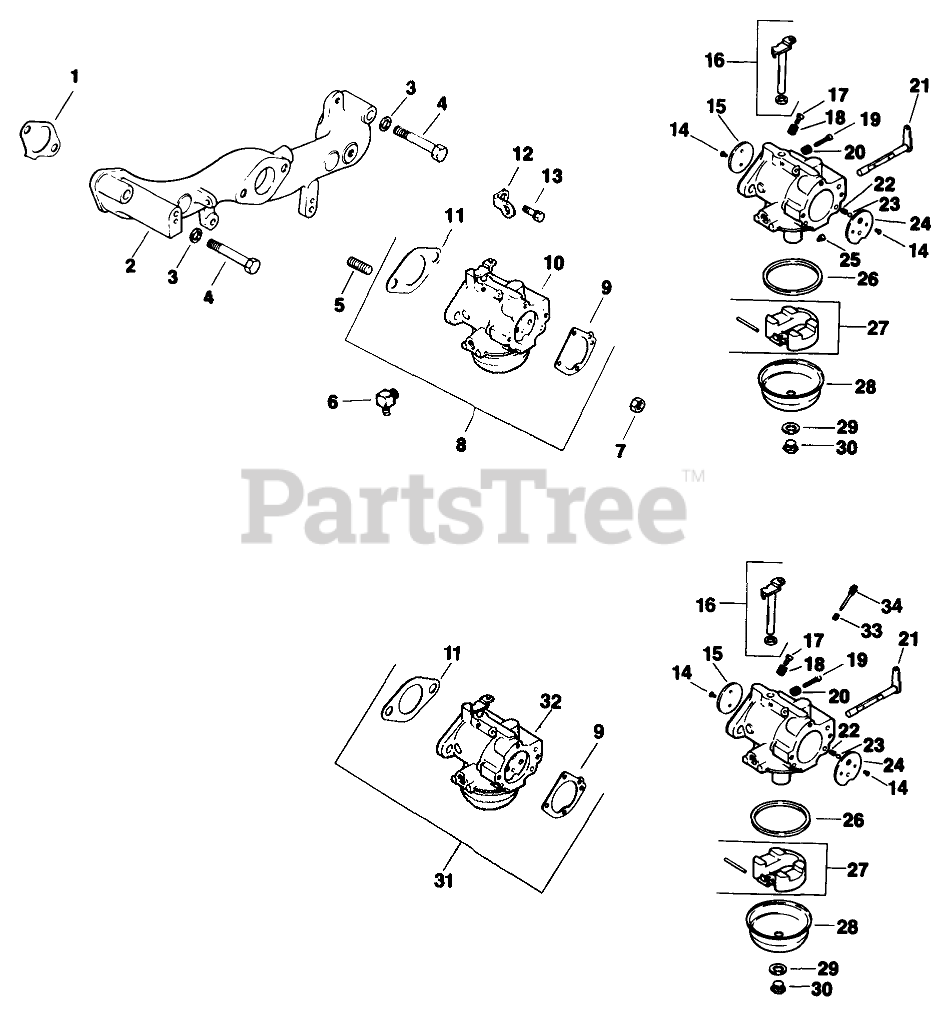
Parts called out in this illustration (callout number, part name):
1	Gasket-Intake
2	Manifold-Intake
3	Washer
4	Screw
5	Clip
6	Connector-Hose
7	Nut
8	CARburetor Kit w/Linkage
9	Gasket-Elbow
10	Carburetor Assembly Ref.
11	Gasket
12	Strap Lifting
13	Screw
14	Screw-Throttle Plate
15	Plate-Throttle
16	Shaft Assembly
17	Valve-Needle
18	Spring
19	Screw
20	Spring
21	Lever-Choke
22	Spring-Choke
23	Ball-Choke
24	Plate-Choke
25	Jet-Main
26	Bowl-Gasket
27	Kit-Float
28	Bowl
29	Gasket-Bowl
30	Screw-Bowl
31	Kit-Carburetor w/Gasket
32	CARburetor Assembly For Information Only
33	Spring
34	Needle-Main Fuel
